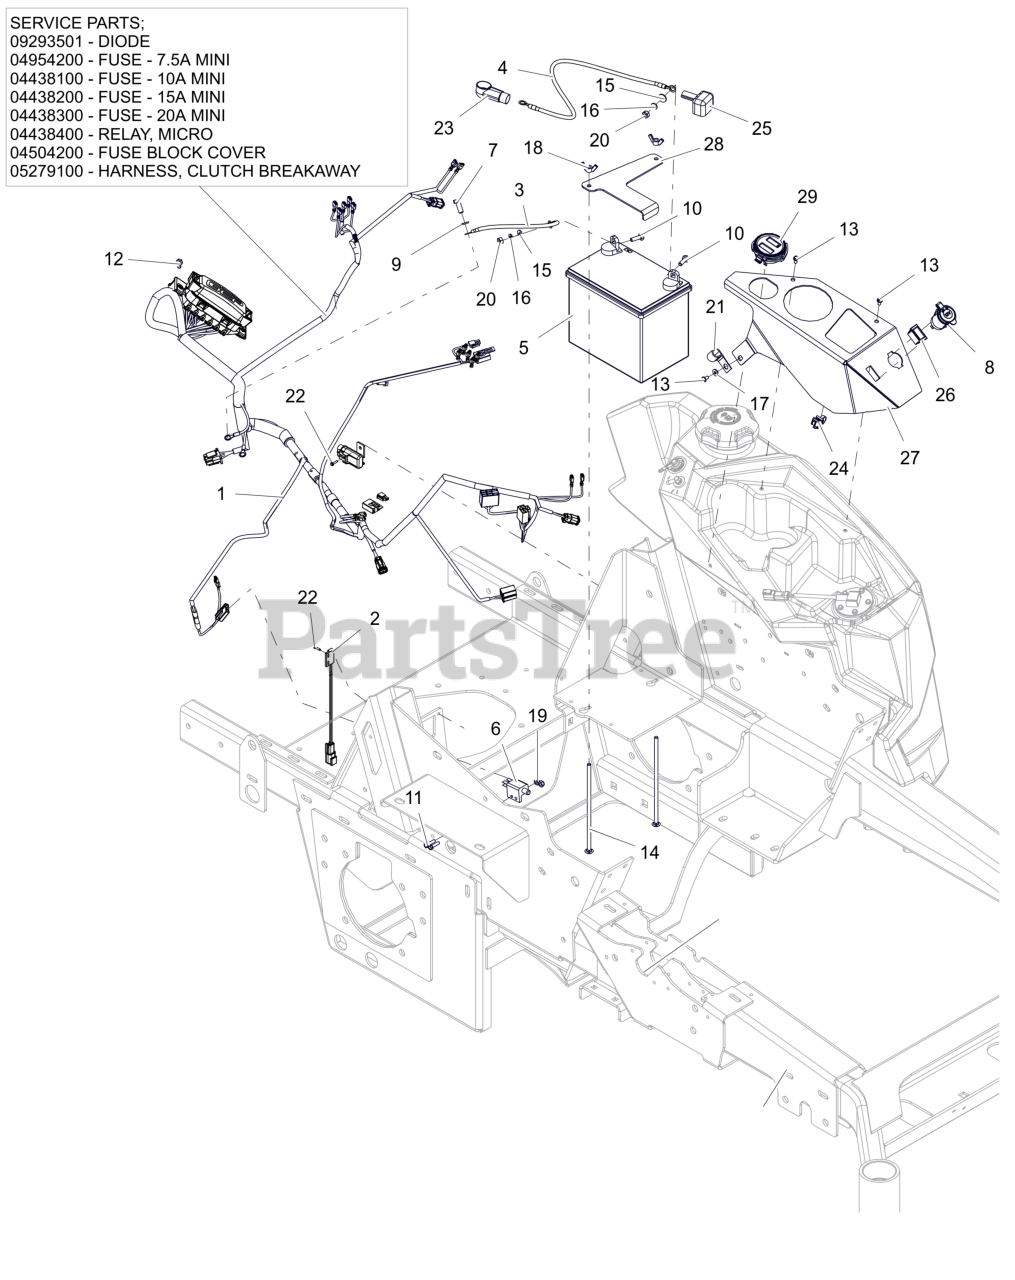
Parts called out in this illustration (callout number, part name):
1	KIT- PT600 HARNESS ROUTING
1	DIODE, CONNECTOR SHELL
1	FUSE, 7.5 AMP MINI-ATC
1	FUSE,10 AMP MINI-ATC
1	FUSE,15 AMP MINI-ATC
1	FUSE,20 AMP MINI ATC
1	RELAY,MICRO5 TERML W/RESISTOR
1	COVER, HARNESS FUSE/RELAY MOD
1	HARNESS, CLUTCH BREAKAWAY
2	SWITCH, MAGNETIC
3	CABLE, NEGATIVE BATTERY 11.5 LNG
4	CABLE, POS W/(2) .312 RING 16.0 LG
5	BATTERY, 300 CCA 10U1L
6	SWITCH- DOUBLE POLE N.O./N.O.
7	BLT, HEX M8-1.25X20 G8.8 ZCC
8	PORT, 12 VOLT POWER
9	WSHR,LK-REG .312X.078 ZCC
10	BLT, HEX .25-20X.75 G5 ZCC
11	BLT, HWH #10-24X.75 ZCC
12	BLT, HEX M6-1X16 G8.8 ZCC
13	SCR-MCH 10-24X.38 HWHSTAINLESS
14	BTL,RHSN .250-20 X 7.5 G5 ZCC
15	WSHR,FLT .281X.625X.065 ZCC
16	WSHR,LK-REG .250X.062 ZCC
17	WSHR-FL-STL .196X.50X.06 ZC120
18	NUT, LK-WING .25-20 ZCC
19	NUT-LK-NYL #10-24 G2 ZCC
20	NUT-STD .250-20 G2 ZCC
22	SCR-TAP #4-40X.50 HWH ZCC
23	BOOT, .65ID POS
24	TIE, EC23 MOUNT W CABLE
25	INSULATOR
26	SWITCH,BLANK
27	PANEL, LH CONTROL (RED)
28	HOLDDOWN, BATTERY (BLACK)
29	DUAL METER
